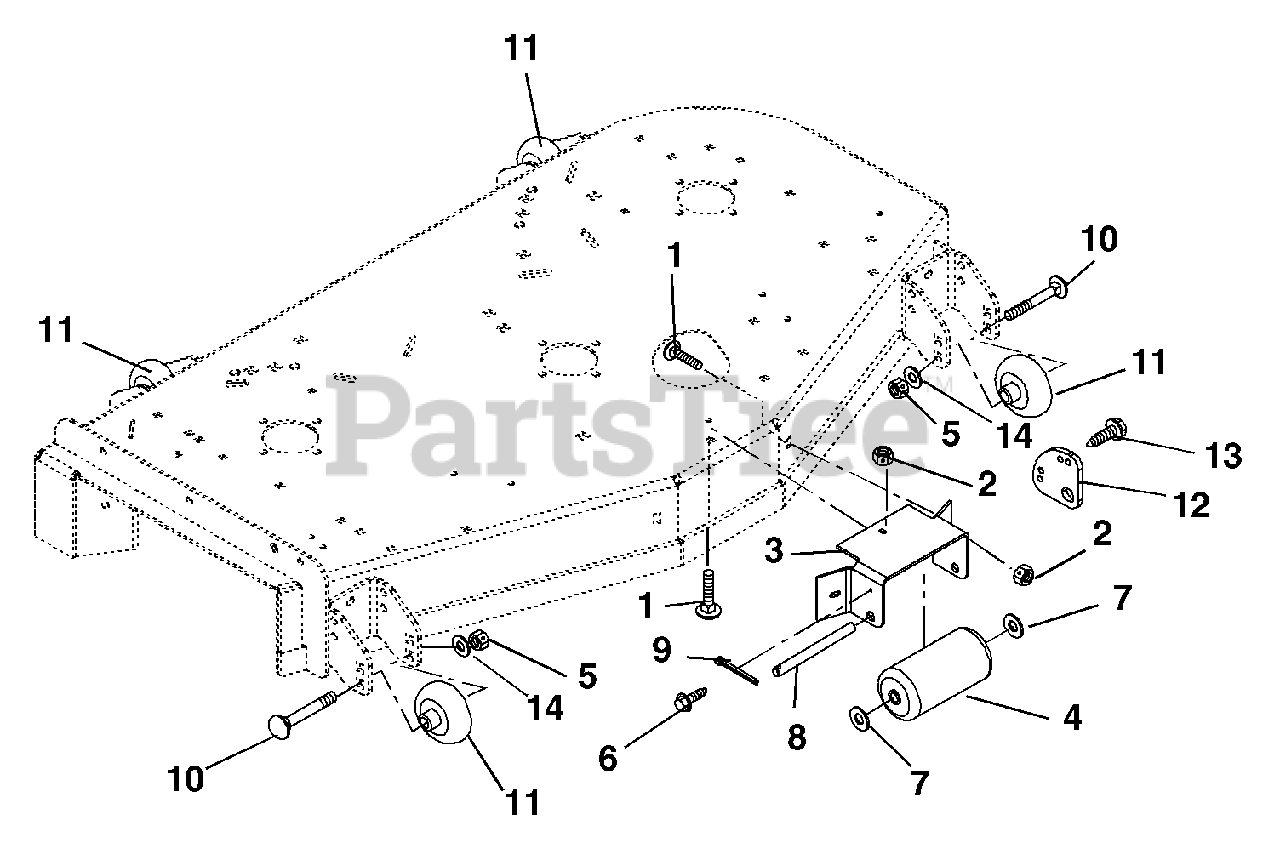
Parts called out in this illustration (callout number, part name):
1	@BLT-RDHDSQNK .38-16X1.00 G5YZ
2	@NUT-LK-TOP-FLG .38-16 YWZC
3	BRACKET - ANTI-SCALP ROLLER
5	@NUT-LK-NYL .50-13 YWZC
6	SCR-TAP .25-20X.75 HWH TR YWZ
7	@WSHR-FL-STL.656X1.31X.095 YWZ
8	PIN, 9.41 X .625
9	@PIN-CTR .25X2.00 YWZC
10	BLT-RDHDSQNK .50-13X5.00 GR5YZ
11	WHEEL, 3X5
12	ANTI-SCALP WASHER - RED
13	SCR-TAP.250-20X.62 HWH BLK ZC
14	@WSHR-FL-STL.531X1.06X.095YWZC
